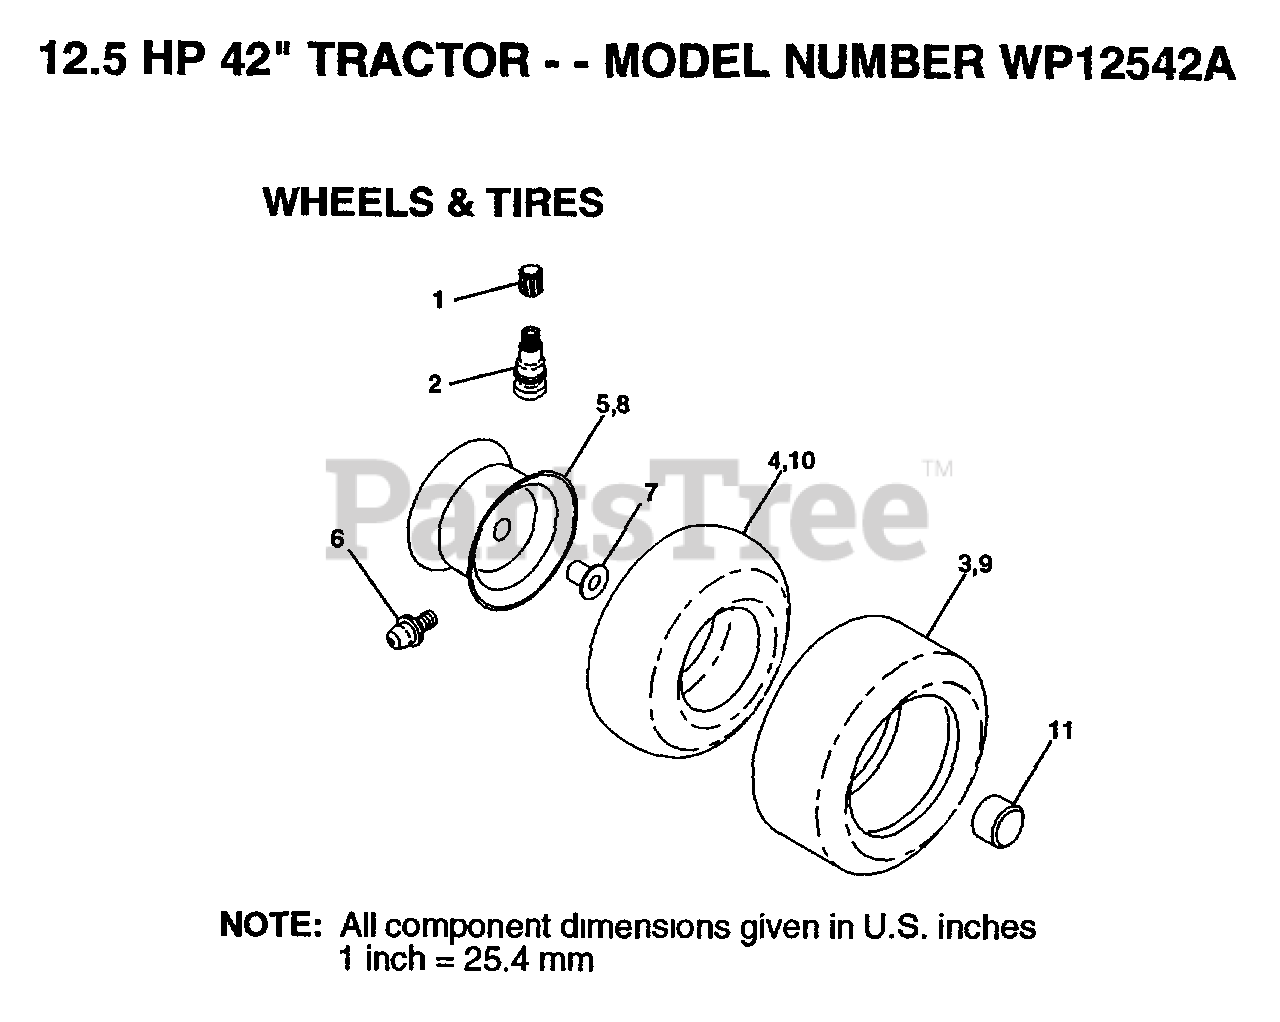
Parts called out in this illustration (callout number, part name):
1	VALVE CAP
2	VALVE STEM LT
4	TUBE.5.3/4.5/6
6	FITTING LT
7	"FLANGE, BEARING"
10	TUBE.18X9.5-8
11	HUB CAP
